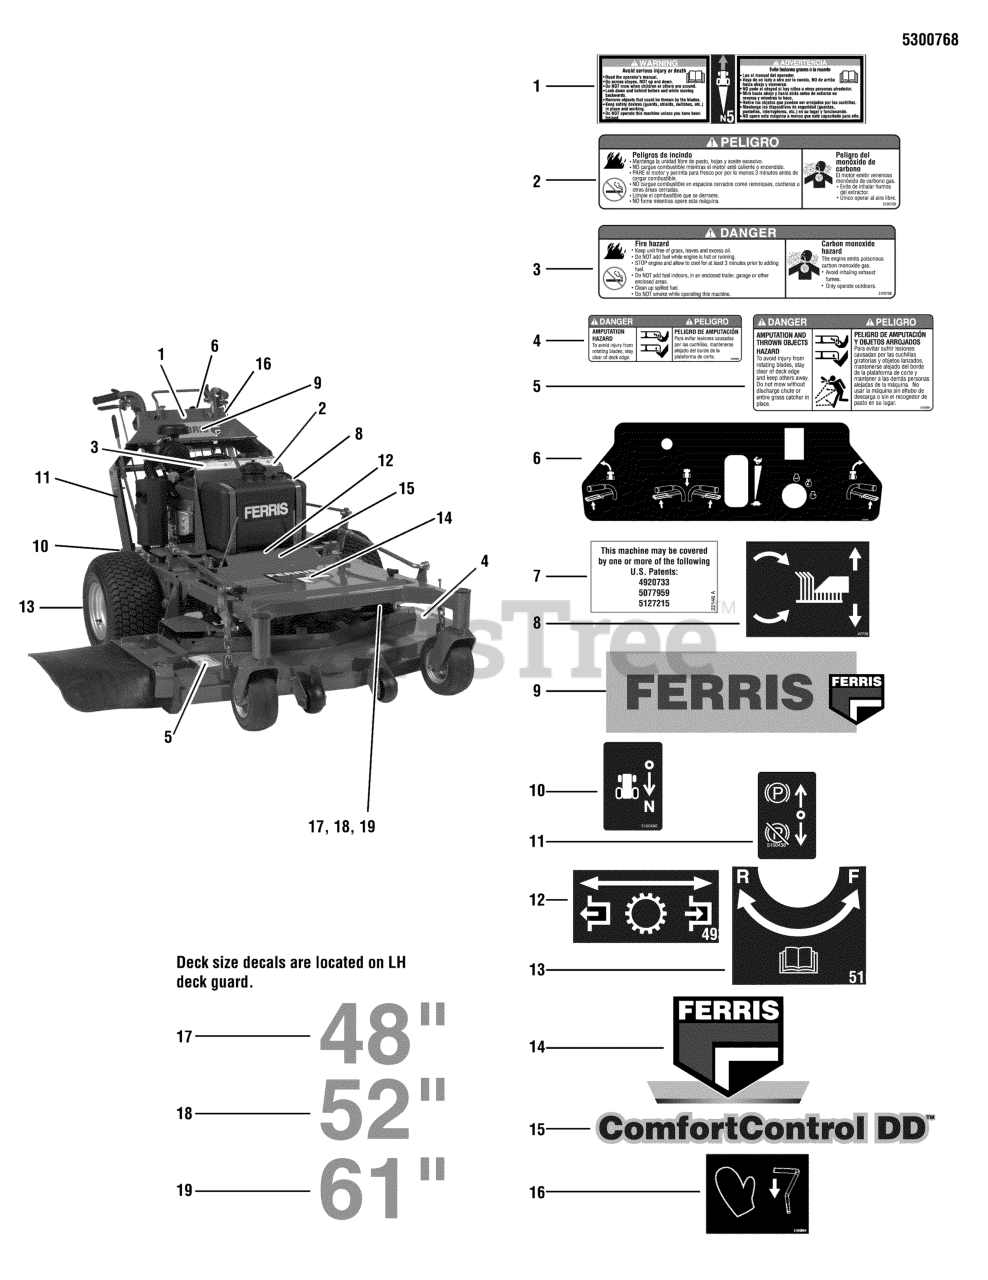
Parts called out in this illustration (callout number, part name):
1	DECAL, WARNING
2	DECAL, DANGER, FIRE (SP)
3	DECAL, DANGER, FIRE
4	DECAL, DANGER, MOWER
5	DECAL, DANGER, MOWER DISCHARGE,8.75X2.13
6	DECAL, CONTROL PANEL
6	DECAL, CONTROL PANEL, WB
7	DECAL, US PATENT, DDS
8	DECAL-CUT HEIGHT ADJUST HYDRO CUT
9	DECAL, FERRIS TEXT & LOGO
10	DECAL, PEDAL
11	DECAL, PARKING BRAKE
12	DECAL, HYDRO RELEASE
13	DECAL, FORWARD / REVERSE
14	DECAL, FERRIS, SHIELD
15	DECAL, COMFORT CONTROL
16	DECAL, AUXILARY OPC
17	DECAL, 48
18	DECAL, 52
19	DECAL, 61"
